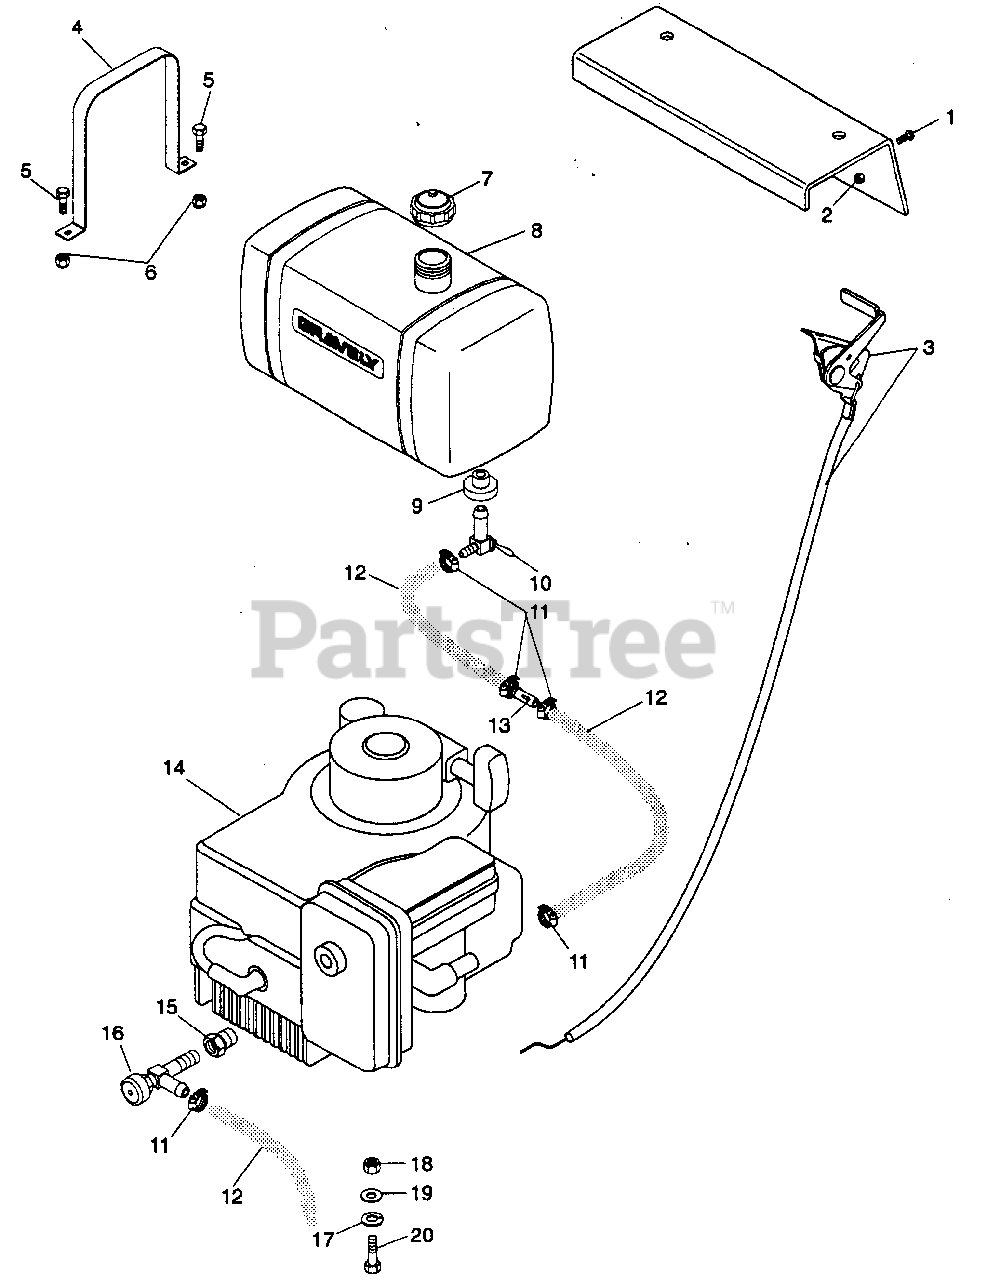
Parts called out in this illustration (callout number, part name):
1	SCR-MCH 10-32 X .50 PHD
2	NUT-LK 10-32 HEX N/INSRT
3	ASSY, THROTTLE CONTROL/CABLE
4	STRP, FUEL TANK
5	BLT-HEX .25-20 X .75 PL GR 5
6	NUT-LK-NYL .250-20 PL
7	CAP, FUEL TANK
8	TANK, FUEL GRAVELY PRO
9	BUSH., F .375 X 1.06 X .625 RB
10	VALVE, BALL SHUT-OFF
11	HOSE CLAMP
12	GAS LINE-BULK
13	FUEL, FILTER
14	ENG, KAWASAKI SPEC GS01
14	ENGINE-14 HP KAWASAKI OHV
15	ADPT, OIL DRAIN
16	COCK, OIL DRAIN
17	WSHR-LOCK .313 X .078 PL
18	NUT-LK-NYL .312-18 PL
19	WSHR-FL-STL 1.344 X .688 X .065
20	BLT-HEX M8 X 1.25 X 30 MM
